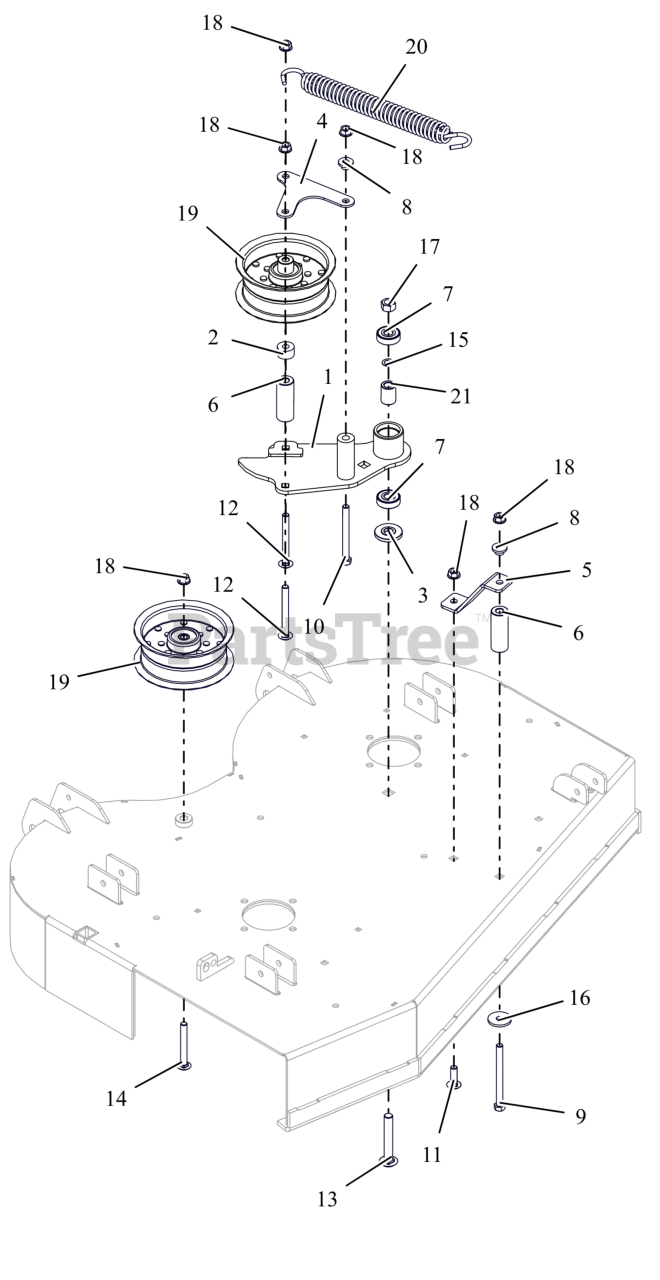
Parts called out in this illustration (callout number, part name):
1	WLDMT, IDLER ARM
2	SPACER .390X1.000X.562
3	SPACER, IDLER ARM
4	BRKT, SUPPORT (BLACK)
5	BRKT, SPRG ANCHOR (BLACK)
6	SPCR, TUBE (BLACK)
7	BRG-BALL .500X1.38X.437
8	BSHG-FLG .385X.500X.875X.406
9	BLT, HEX 0.375-16X4.25 GR5 ZCC
10	BLT, HEX 0.375-16X3.75 GR5 ZCC
11	BLT,RHSSN .38-16X1.25 G5 ZCC
12	BLT,RHSSN .38-16X3.50 G5 ZCC
13	BTL,RHSSN .500-13 X 3.25 G5 ZCC
14	BTL,RHSSN .375-16 X 3 G5 ZCC
15	WASHER, .500X.750X.020 THRUST
16	WSHR,FLT .406X1.375X.135 ZCC
17	NUT,LK-CTR .50-13 GA ZCC
18	NUT-LK-CTR-FLG .375-16 GF ZCC
19	PULLEY, FLAT 5.00X2.36X.375
20	SPRING, EXTENSION
21	SPACER .510 X .867 X 1.1485
